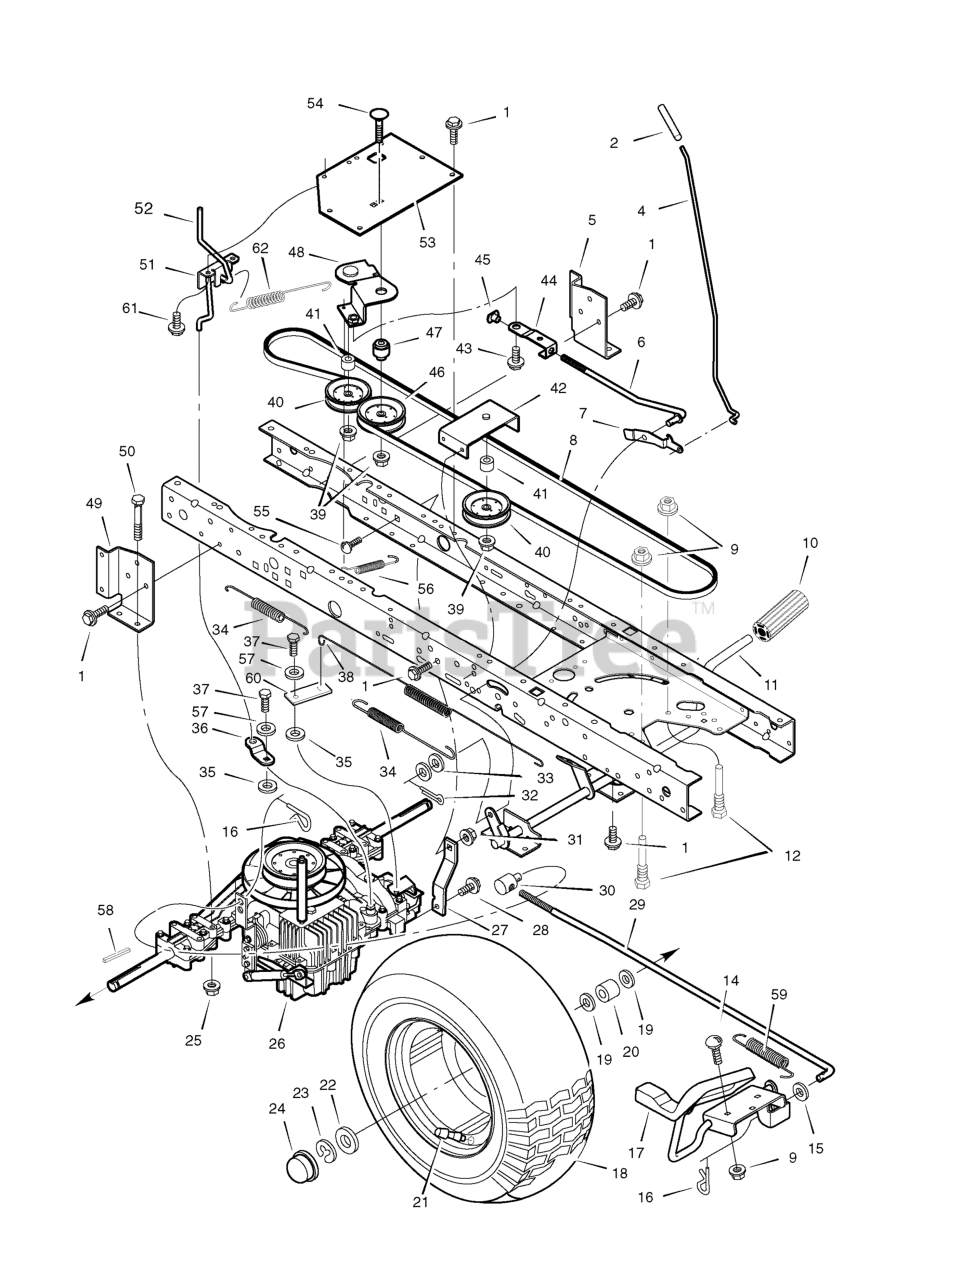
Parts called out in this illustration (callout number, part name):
2	Grip, Parking Brake
4	Rod, Parking Brake
5	Bracket, Left Transaxle
6	Rod, Clutch
7	Latch, Parking Brake
8	V-Belt, Drive
9	Nut, Flange
10	Pedal, Brake/Clutch
11	Assembly, Brake Pedal
12	Screw, Guide
14	Bolt, Carriage
16	Pin, Hair
17	Pedal Assembly, Hydro
18	Wheel & Tire Ass'y, Rear
21	Stem, Valve
24	Cap, Hub
25	Nut, Centerlock
26	Transaxle, Peerless Hydro **
27	Strap, Torque
29	Rod, Control
30	Nut, Adjusting
31	Nut, Centerlock
32	Pin, Cotter
34	Spring, Extension
36	Arm, Disconnect
37	Capscrew
38	Spring, Brake
39	Locknut, Flange
40	Pulley, Idler
42	Bracket, Idler Assembly
43	Bolt, Shoulder
44	Link, Clutch
45	Nut, Tee
46	Pulley, Idler
47	Bushing, Pivot
48	Arm Assembly, Idler
49	Bracket, Right Transaxle
50	Bolt, Hex
51	Bracket, Dump Valve
52	Rod, Roll Release
53	Bracket, Idler Pivot
54	Bolt, Carriage
55	Bolt, Carriage
56	Spring, Clutch
58	Key, Square 3/16"
60	Arm, Break
61	Screw - Tri, 5/16 - 18 X .50
62	Spring Section (Dump)
